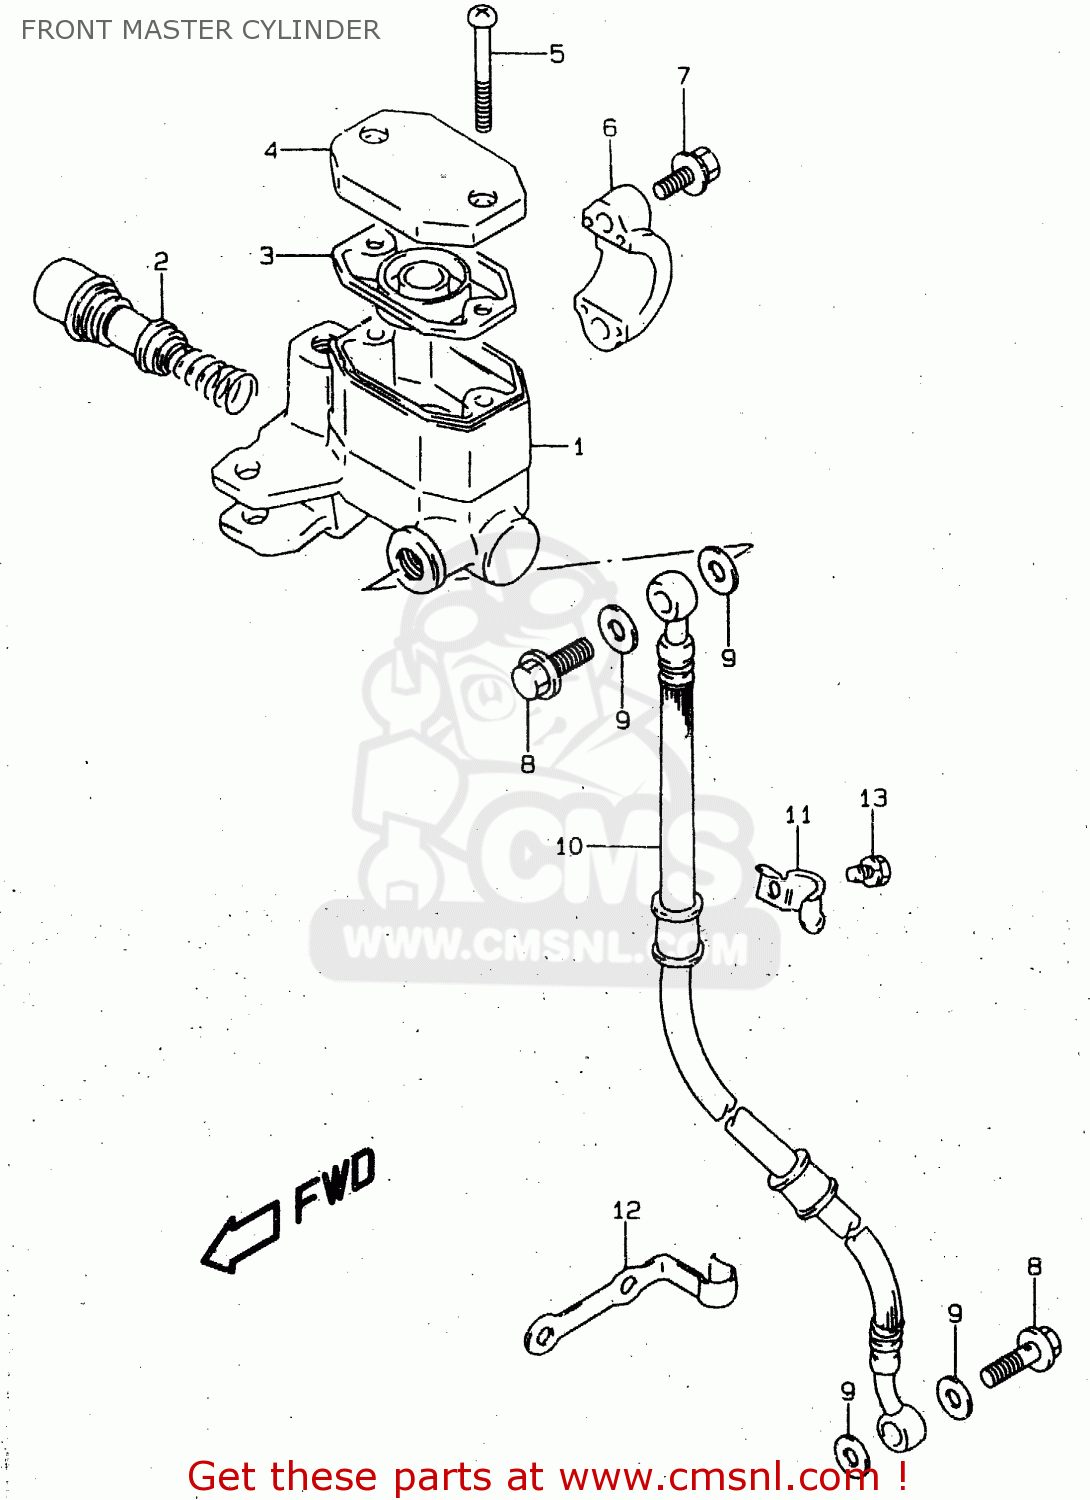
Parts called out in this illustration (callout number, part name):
1	CYLINDER ASSY,FR MASTER
2	PISTON/CUP SET
3	DIAPHRAGM
4	CAP
5	SCREW
6	HOLDER
7	BOLT(6X25)
8	BOLT UNION
9	WASHER(10X15X1.5)
10	HOSE,FR BRAKE
11	CLAMP,BRAKE HOSE
12	CLAMP,BRAKE HOSE
13	BOLT
